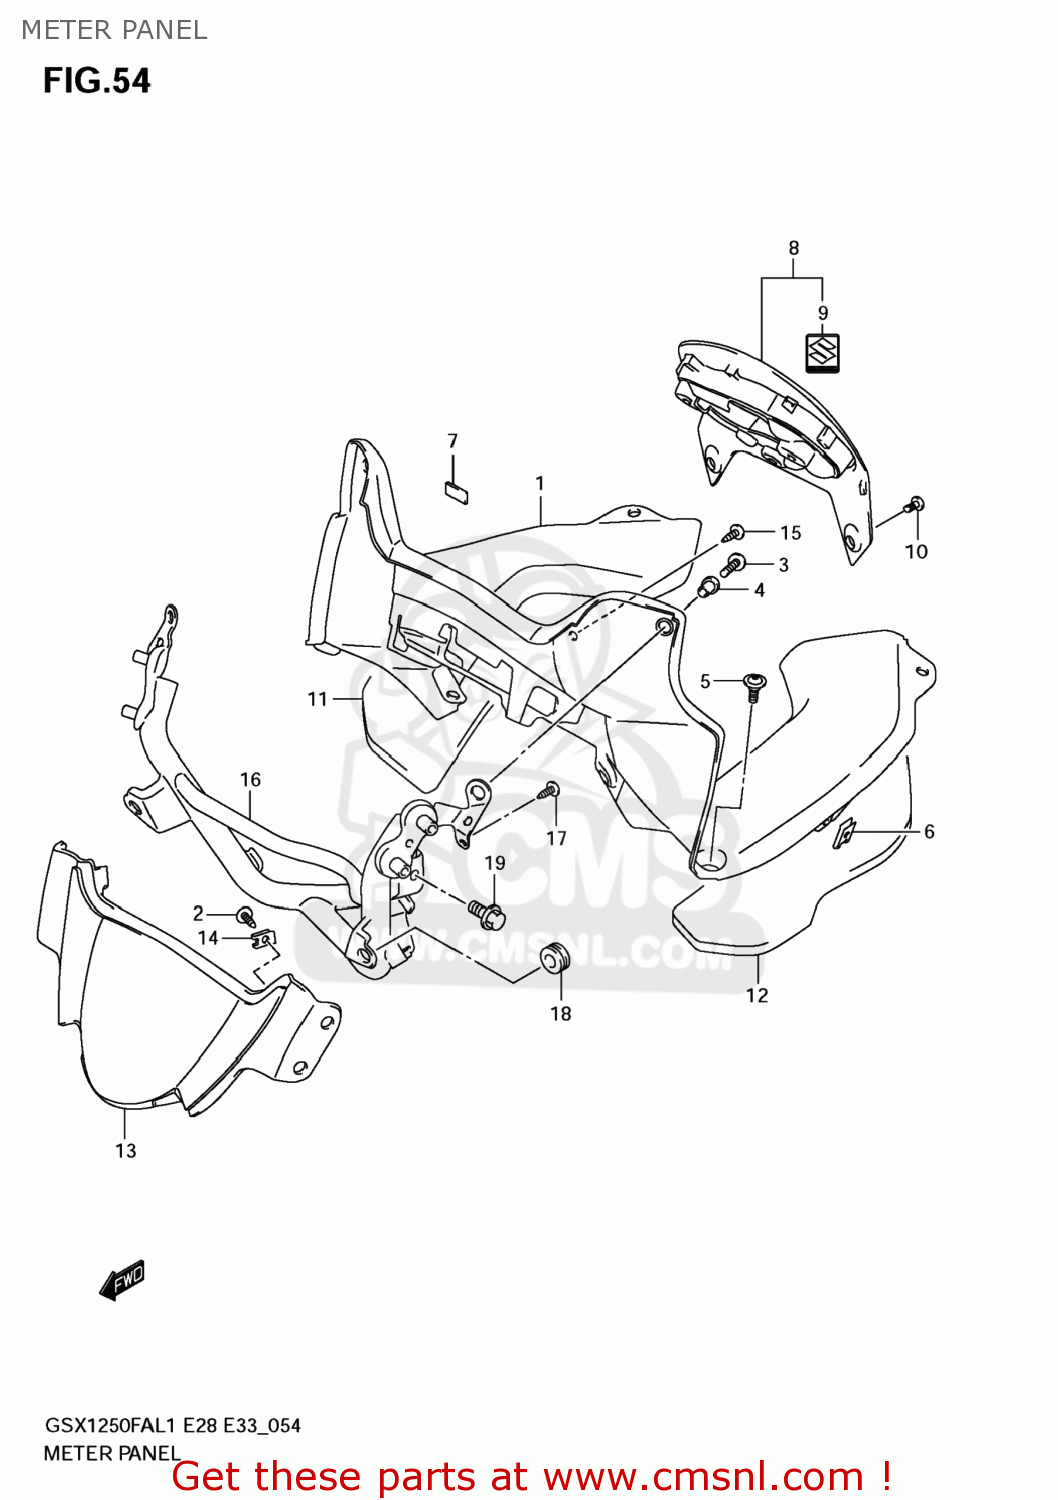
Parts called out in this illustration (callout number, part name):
1	PANEL,METER
2	SCREW
3	SCREW
4	NUT
5	BOLT(5X13)
6	NUT
7	CUSHION
8	LID,METER PANEL
9	EMBLEM,S
10	SCREW(6X10)
11	CUSHION,PANEL,R
12	CUSHION,PANEL,L
13	PANEL,METER FR
14	NUT
15	SCREW
16	BRACE,COWLING
17	SCREW
18	CUSHION
19	BOLT
